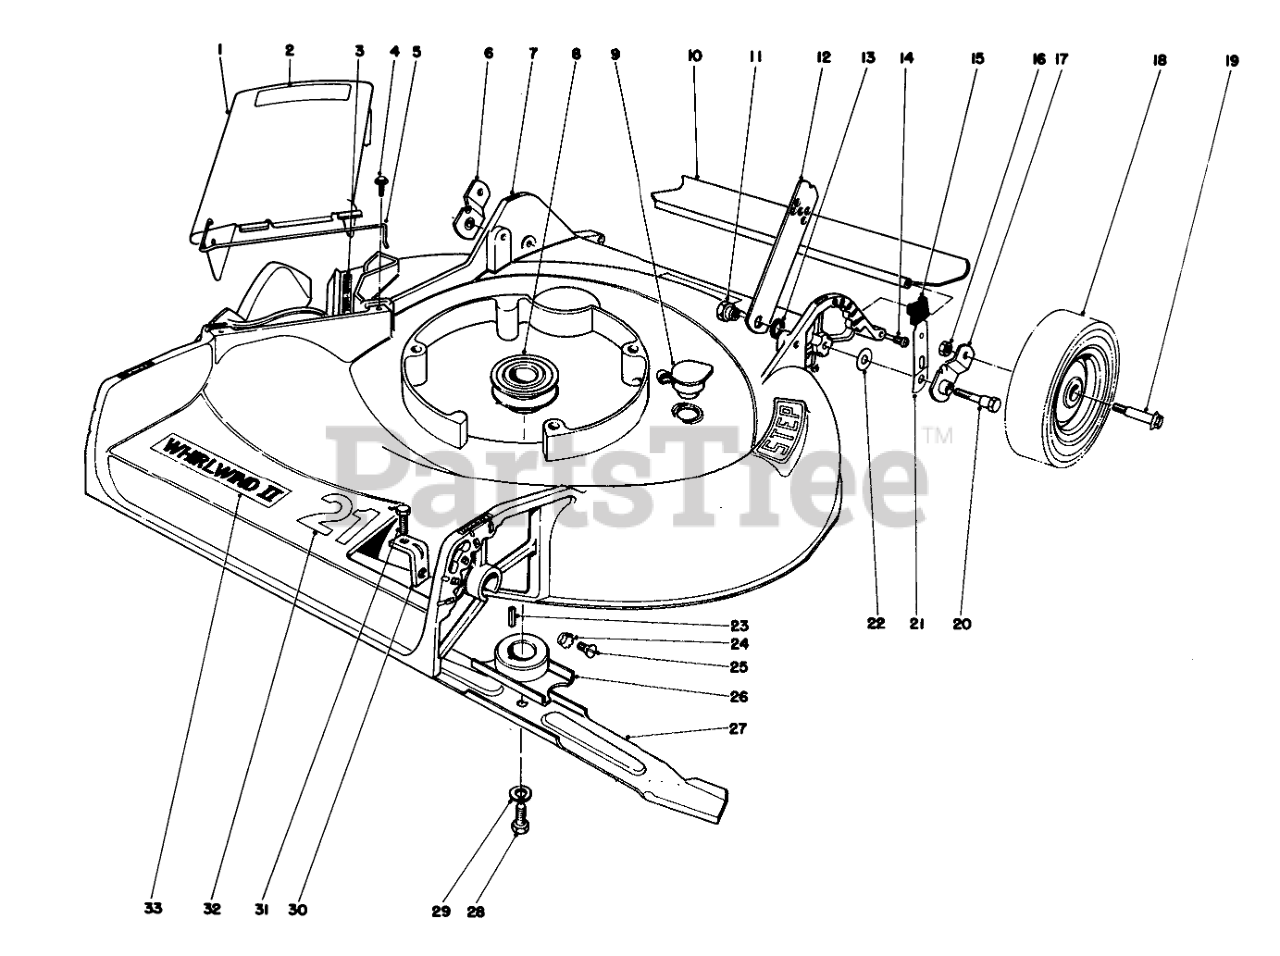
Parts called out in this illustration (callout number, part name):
1	Deflector Assembly (Incl. Ref. 2 & 5)
2	Caution Decal
3	Decal
4	SCREW
5	SPRING HINGE
6	Pivot Arm
7	Housing
8	DRIVER PULLEY
9	WASHOUT PLUG
10	REAR SAFETY SHIELD 21
11	HANDLE PIVOT NUT
12	HANDLE LATCH
13	HANDLE LATCH SPACER
14	SAFTEY SHIELD SCREW
15	KNOB-ARM
16	Nut
17	Pivot Arm
18	Wheel & Tire Assembly
20	PIVOT SCREW
21	SPRING ARM ASM
22	WASHER-PIVOT
23	KEY-SQUARE
24	Lockwasher
25	5/16-18X5/8 FLT HD MS
26	Blade Retailer
27	Blade
28	SPECIAL SCREW
29	WASHER-LOCK
30	Bracket-Gear Box
31	SCREW-HH
32	Decal 21"
33	Decal Whirlwind
